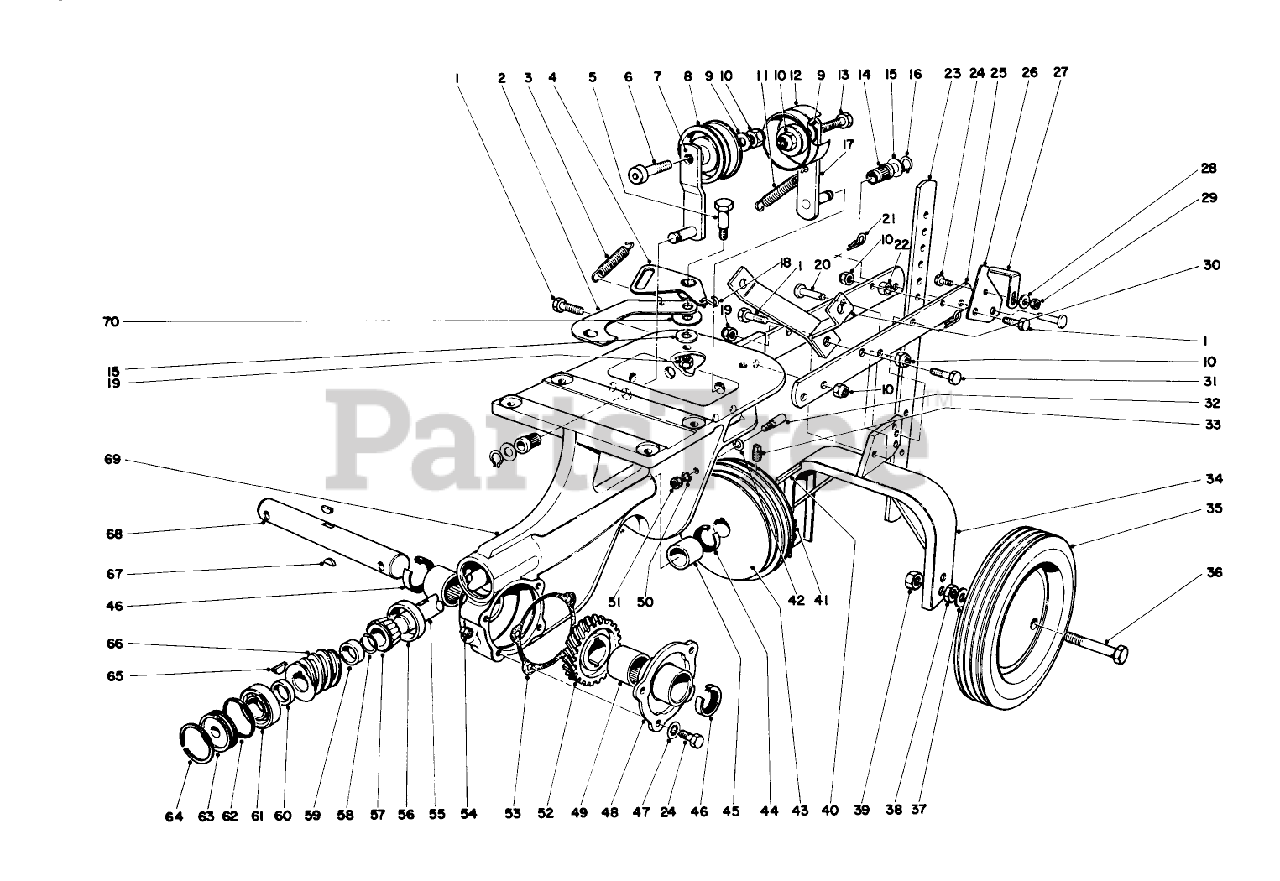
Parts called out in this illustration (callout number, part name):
1	SCREW-HH
2	Rev. Link
3	Spring
4	Bellcrank
5	SCREW-SHOULDER, HH
6	Capscrew
7	IdlerArm
8	PULLEY IDLER
9	WASHER-FLAT
10	NUT-LOCK, CONE
11	Spring
12	IDLER PULLEY
13	SCREW-HH
14	IDLER BRG
15	WASHER-PLAIN
16	RING-RETAINING, EXT
17	Idler Arm
18	S Hook
19	NUT-LOCK, CONE
20	TINE PIN
21	PIN-COTTER, HAIR
22	Spacer
23	DEPTH GAGE
24	SCREW-HH
25	Drawbar
26	Hinge Latch
27	Drag Bar Latch
28	WASHER-FLAT
29	NUT-LOCK, CONE
30	Handle Support
31	SCREW-HH
32	Belt Guide
33	SCREW-SET, HSH
34	Wheel Bracket
35	Wheel
36	Axle
37	WASHER-FLAT
38	NUT-JAM
39	1/2-13 CONELOCK NUT
40	KEY-SQUARE
41	Pulley
42	WASHER-FLAT
43	Pulley
44	SEAL-OIL
45	BUSHING
46	SEAL-OIL
47	WASHER-LOCK
48	Cover
49	Bearing
50	WASHER-LOCK/EXT
51	NUT-JAM
52	WORM WHEEL
53	GASKET
54	PLUG-PIPE, SQH
55	WORM SHAFT
56	1.750 ROLLER BRG CUP
57	3/4 ROLLER BRG CONE
58	RETAINER RING
59	WORM SHF REAR SPACER
60	SPACER
61	.750 BALL BEARING
62	O-RING
64	INTRNL RETAINING RING
65	KEY-WOODRUFF
66	WORM GEAR
67	KEY-WOODRUFF
68	WORM WHEEL SHAFT
69	Chassis
70	WASHER-FLAT
